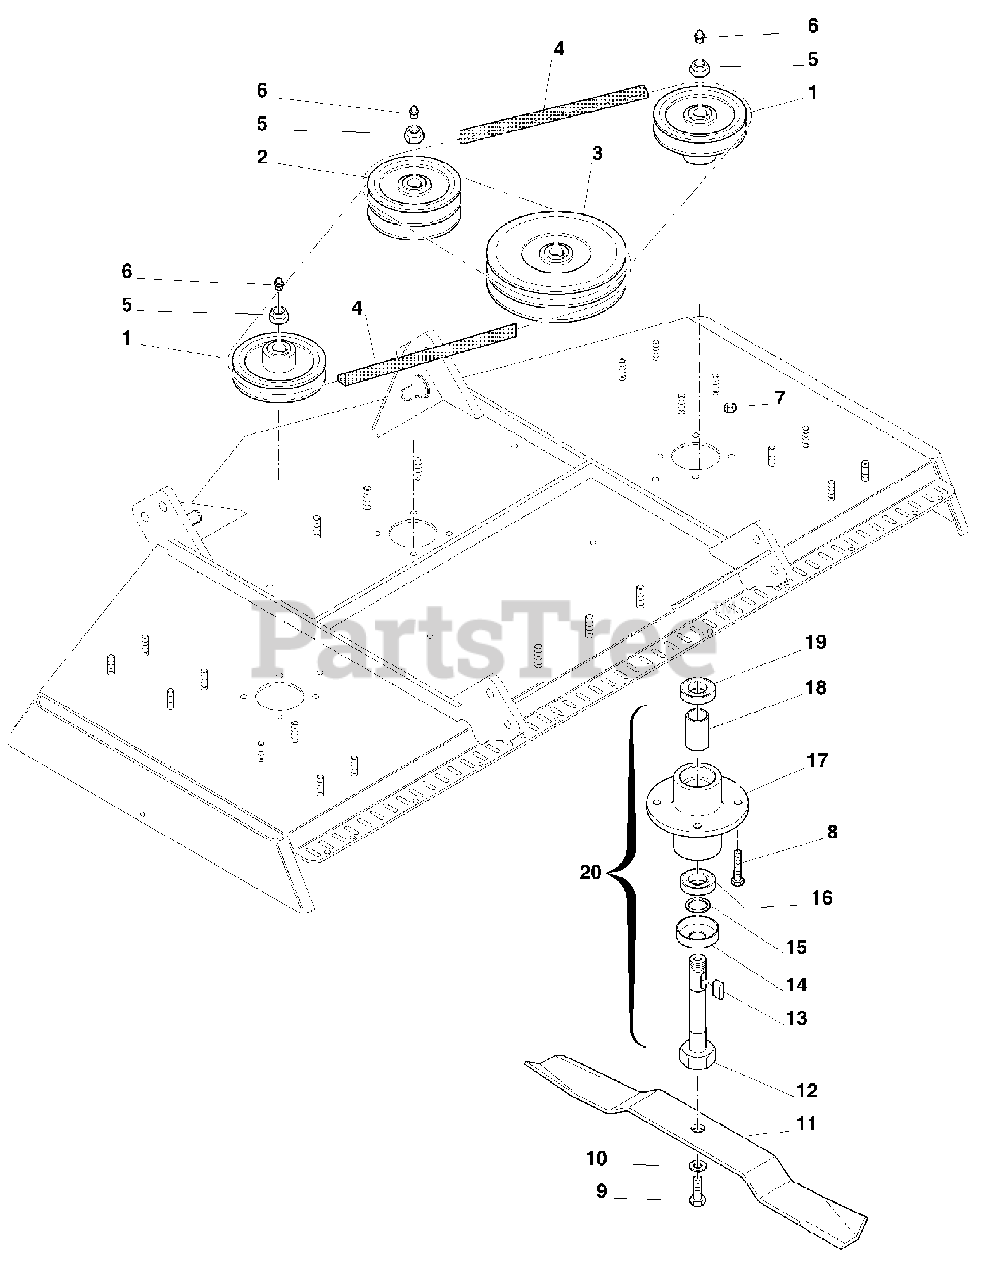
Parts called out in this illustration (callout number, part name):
1	Pulley SPB 160x1 FML72
2	Pulley SPB 160x2 FML72
3	Pulley SPB 250x2
4	Belt 5VX850 FML72
5	Nut M25
6	Grease fitting
7	Nut M10
8	Bolt TE 10x30
10	Disc spring
11	Standard blade FML72
12	Spindle shaft
13	Key 8x7x25
14	Cover
15	Spacer washer
16	Bearing 6205-ZZ
17	Spindle
18	Spacer
19	Bearing 6205-Z
20	Spindle assembly
